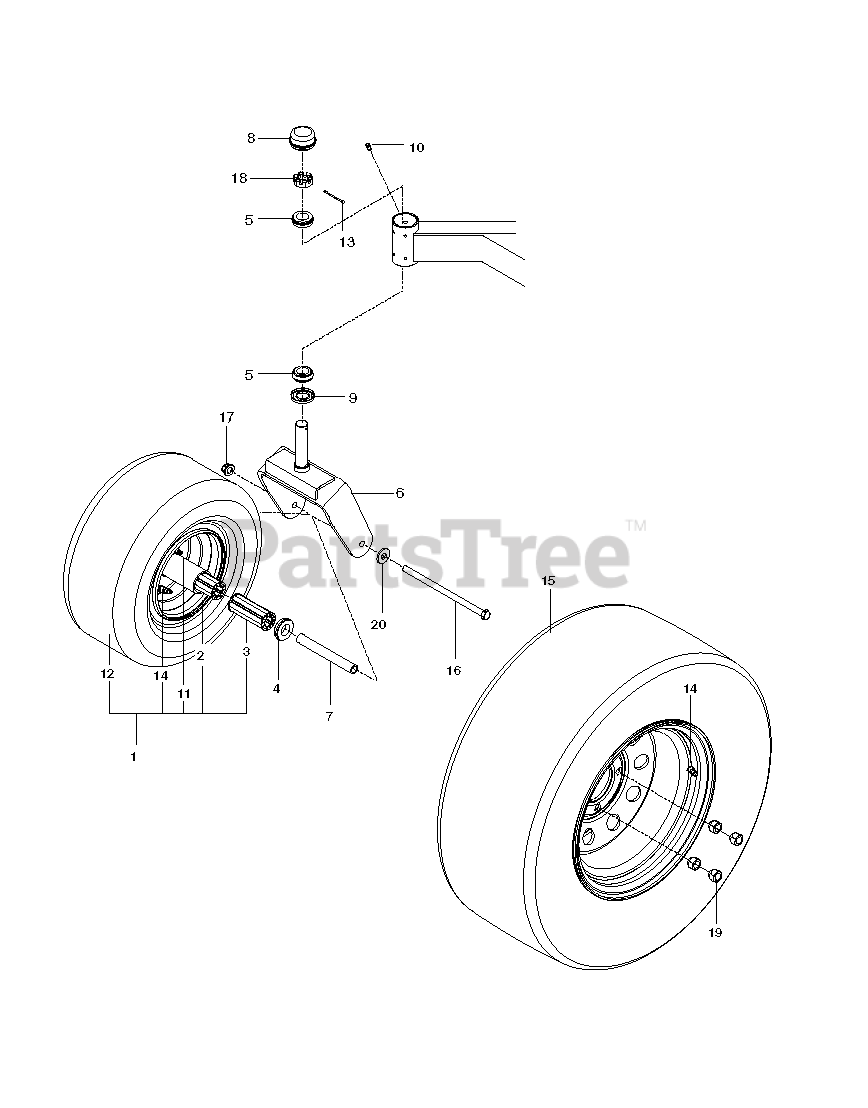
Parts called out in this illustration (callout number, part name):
1	TIRE.ASSEM.CASTER.13X6.5-6.SIL
2	WHEEL.6X4.50.CASTER.SILVER
3	ROLLER BEARING-CAGED 3 1/4'
4	BEARING RETAINER
5	TAPERED ROLLER BRG
6	YOKE, CASTER, BLUE
7	SPACER, PIVOT
8	GREASE CAP
10	ZERK
11	ZERK
12	TIRE.13X6.50-6.4.PLY
13	COTTER PIN 1/8 X 2
14	VALVE STEM TR-412
15	RP WHEEL.ASM.23X10.5-12.TURFMA
16	HEX SCREW 1/2-13 X 9.5 GR5
17	NUT, 1/2-13 HEX FLG NYLOC ZD
18	NUT 1"C HEX SLOTTED
19	LUG NUT 1/2F
20	WASH USS FLAT 1/2
